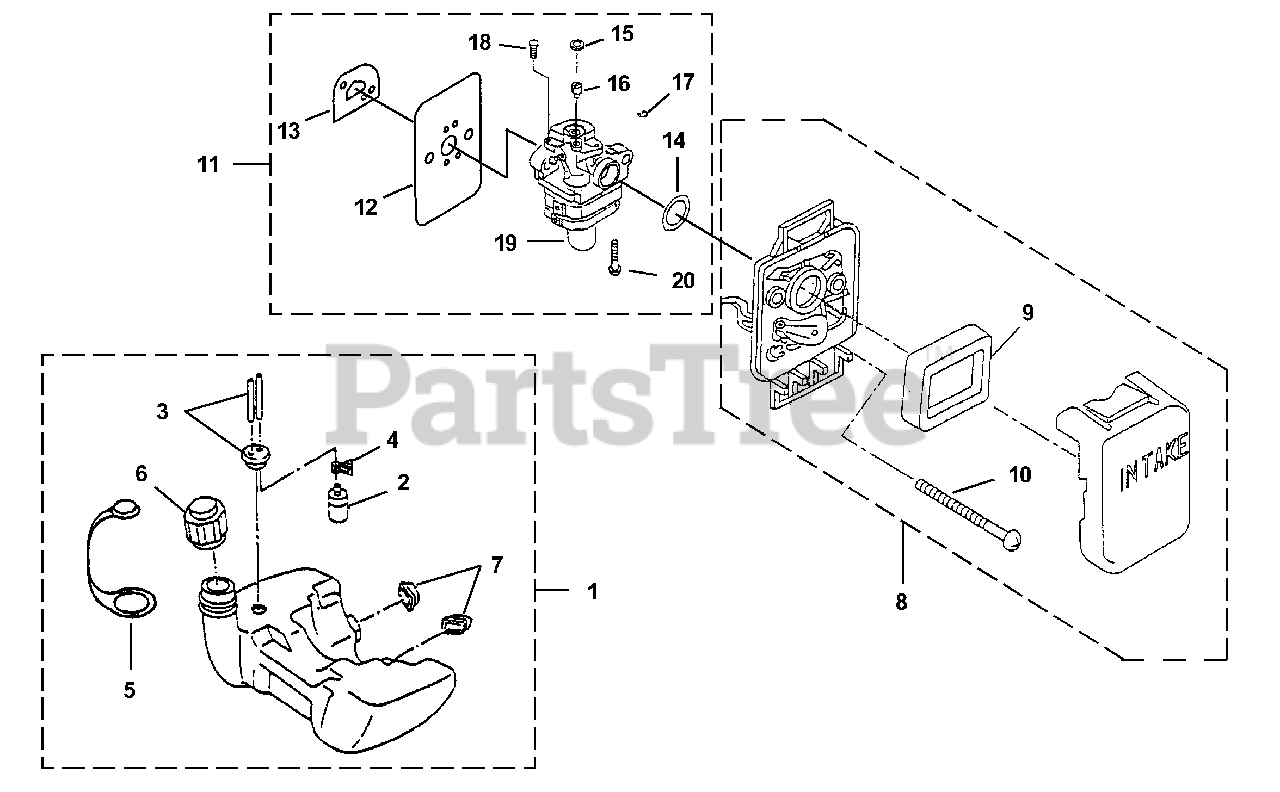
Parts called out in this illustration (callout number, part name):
1	FUEL TANK ASSEMBLY
2	FILTER-Fuel
4	CLAMP-Hose
5	CAP-Retainer
6	CAP-Fuel
7	RUBBER BUMPER KIT
8	AIR FILTER ASSEMBLY
9	FILTER-Air
10	SCREW ASSEMBLY (M5 x 14)
11	CARBURETOR ASSEMBLY
12	GASKET-Carburetor
13	GASKET-Heat Dam
14	RING-Packing
16	SWIVEL-Throttle Cable
19	PUMP-Primer
20	SCREW-Primer Cover
